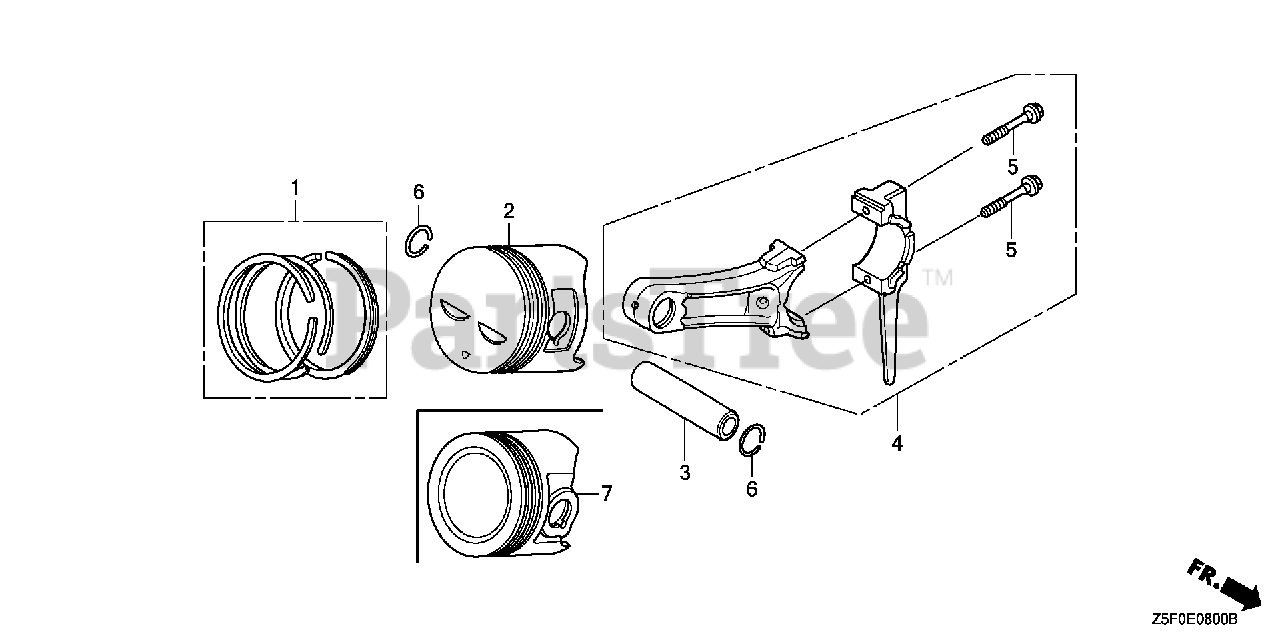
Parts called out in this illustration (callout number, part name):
1	RING SET, PISTON (STD) (TEIKOKU)
1	RING SET, PISTON (STD) (NIPPON)
1	RING SET, PISTON (OS 0.25) Use from Engine SN 4081305.
1	RING SET, PISTON (0.25) (TEIKOKU)
1	RING SET, PISTON (OS 0.50) Use from Engine SN 4081305.
1	RING SET, PISTON (0.50) (TEIKOKU)
1	RING SET, PISTON (0.75) Use from Engine SN 4081305.
1	RING SET, PISTON (0.75) (TEIKOKU)
2	PISTON (STD)
2	PISTON (OS 0.25)
2	PISTON (0.25)
2	PISTON (OS 0.50)
2	PISTON (0.50)
2	PISTON (0.75)
3	PIN, PISTON
4	ROD ASSY., CONNECTING (STD)
4	ROD ASSY., CONNECTING (Honda Code 2110153). (US 0.25)
5	BOLT, CONNECTING ROD
6	CLIP, PISTON PIN (18MM)
